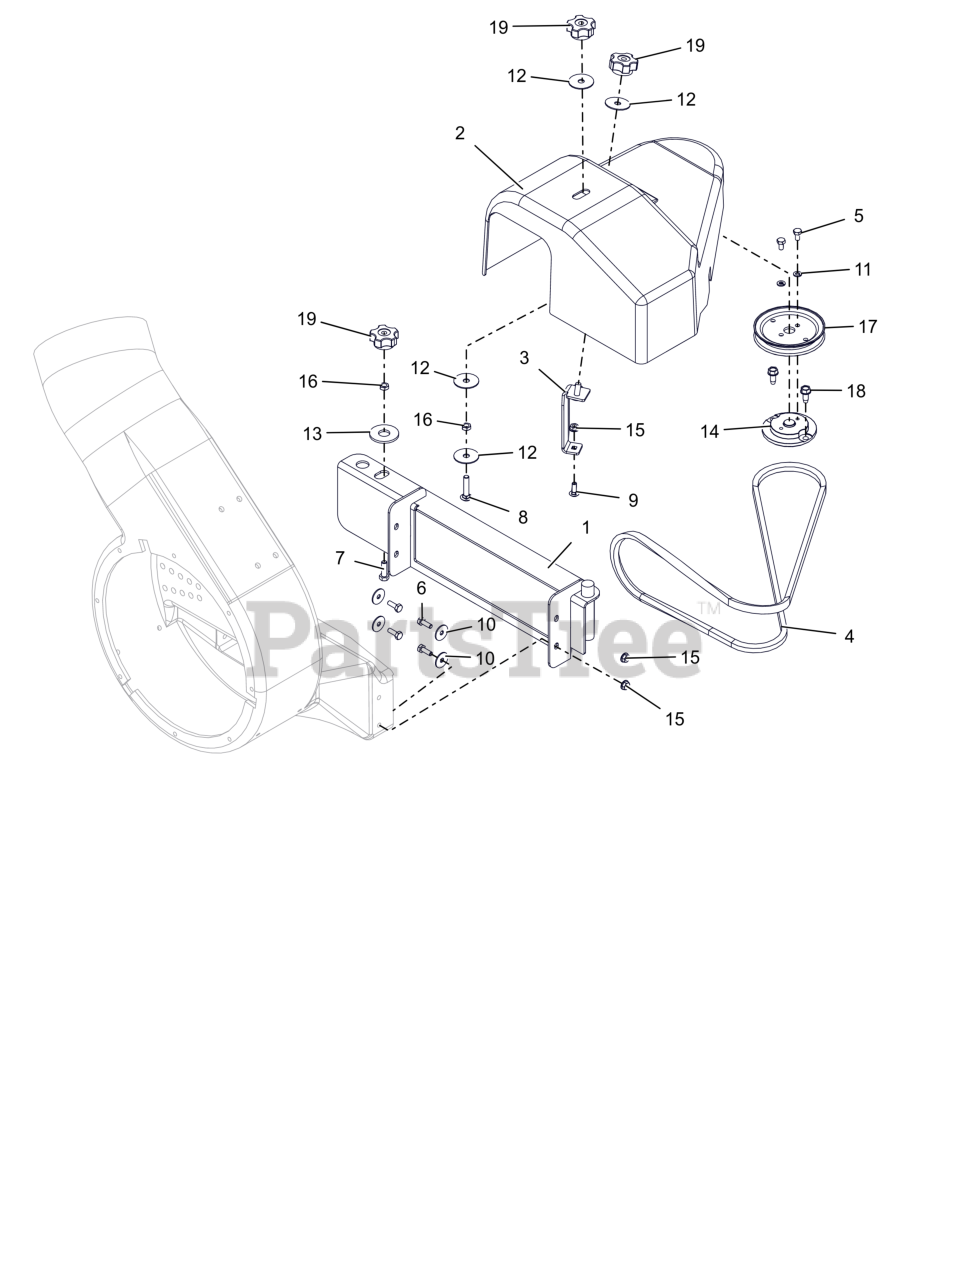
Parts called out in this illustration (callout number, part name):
1	WLDMT, PUMP MOUNTING (BLACK)
2	KIT, COVER W/DECAL
3	WLDMT, BAGGER BELT COVER BRKT
4	V-BELT, 48"
5	BLT,HEX .25-20X.50 G5 ZCC
6	BLT, HEX .25-20X.75 G5 ZCC
7	BLT, HEX .31-18X1.00 G8 ZCC
8	BLT,RHSN .31-18X1.50 G5 ZCC
9	BLT, RHSN .25-20X.750 G5 ZCC
10	WSHR,FLT .281X1.000X.063 ZCC
11	WSHR,LK-REG .250X.062 ZCC
12	WSHR,FLT .380X1.50X.062 ZCC
13	WSHR,FLT .688X1.75X.134 ZCC
14	ADAPTOR, BAGGER SHEAVE
15	NUT-LK-TOP-FLG .250-20 GF ZCC
16	NUT-JAM .312-18 G2 ZCC
17	SHEAVE, SPINDLE (4.25 HA )
18	SCR,TAP .312-18X.75 HWH TR ZCC
19	KNOB-CLAMPING, .312-18 NYLOC
